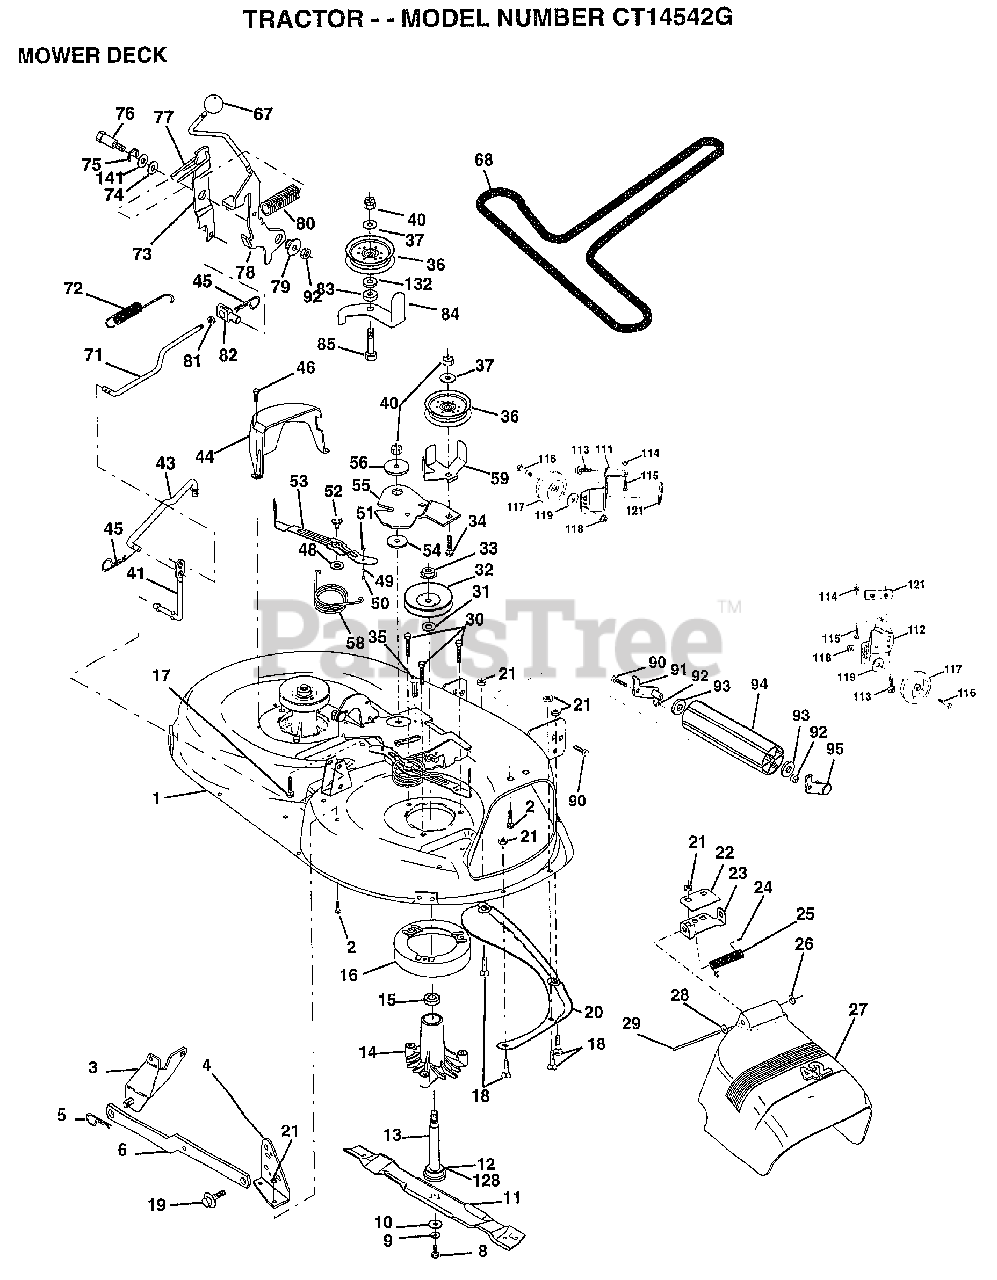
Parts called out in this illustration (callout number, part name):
1	"HOUSING ASSY.42"""
2	BOLT
3	BRKT ASM SWAY BAR
4	BRKT DECK SW BAR
8	BLADE BOLT
10	WASHER.HARD.BLADE
11	"BLADE.42"" HIPERF"
12	BEARING.BALL
14	HSG ASM MANDREL
15	BEARING
16	STRIPPER RND MWR
17	BOLT RDHD 3/8-16
18	BOLT
19	BOLT SHD 5/16-18
20	BAFFLE VORTEX 42
22	STIFFENER BRKT
23	DEFLECTOR BRKT
24	CAP-SLEEVE LT
25	SPRING TORSION
26	NUT PUSH M
27	DEFLECTOR.SHIELD
28	WASHER
29	HINGE ROD
30	"SCREW-THD ROLL,WA"
31	WASHER
32	PULLEY.MANDREL.42
34	BOLT
35	XMAS TREE FASTNER
36	FLAT IDLER PULLEY
37	WASHER
41	PIVOT ROD
43	ROD CLUTCH W/NIBS
44	GUARD MAND LH BLK
45	RETAINER M
46	SCREW.1/4-20X5/8
48	HARD SMALL WASHER
49	ROLLER ASM-CAM
50	SHOULDER BOLT
51	LOCKNUT
52	BOLT.SHLD.5/16-18
53	BRAKE PAD ARM ASM
54	HARDENED WASHER
55	ARM-IDLER
56	SPACER RETAINER
58	SPRING TORSN BRAK
59	GUARD IDLER TUV
67	KNOB.RD.7/16-14
68	BELT.V.T-PATH
71	ROD CLUTCH 38/42
72	RETURN SPRING
73	CLUTCH ARM SECOND
74	WASHER
75	RING
76	SHOULDER BOLT
77	SPRING KEEPER
78	LEVER.ASM.CLUTCH
79	BUSHING
80	SPRING.CLUTCH.MWR
81	NUT
82	TRUNION ADJ
83	WASHER
84	"KEEPER-BELT,FIXED"
85	BOLT
90	BOLT, HEX 5/16-18 X 1-1/2
92	NUT
93	WASHER
111	BRACKET.GWHL.LH.
112	BRACKET.GWHL.RH.
113	SCREW
116	BOLT M
117	WHEEL.GUAGE
118	LOCKNUT
119	WASHER
121	BRACKET.EXTRD.GWL
128	WASHER.FELT.
132	WASHER GT
141	WASHER .T
